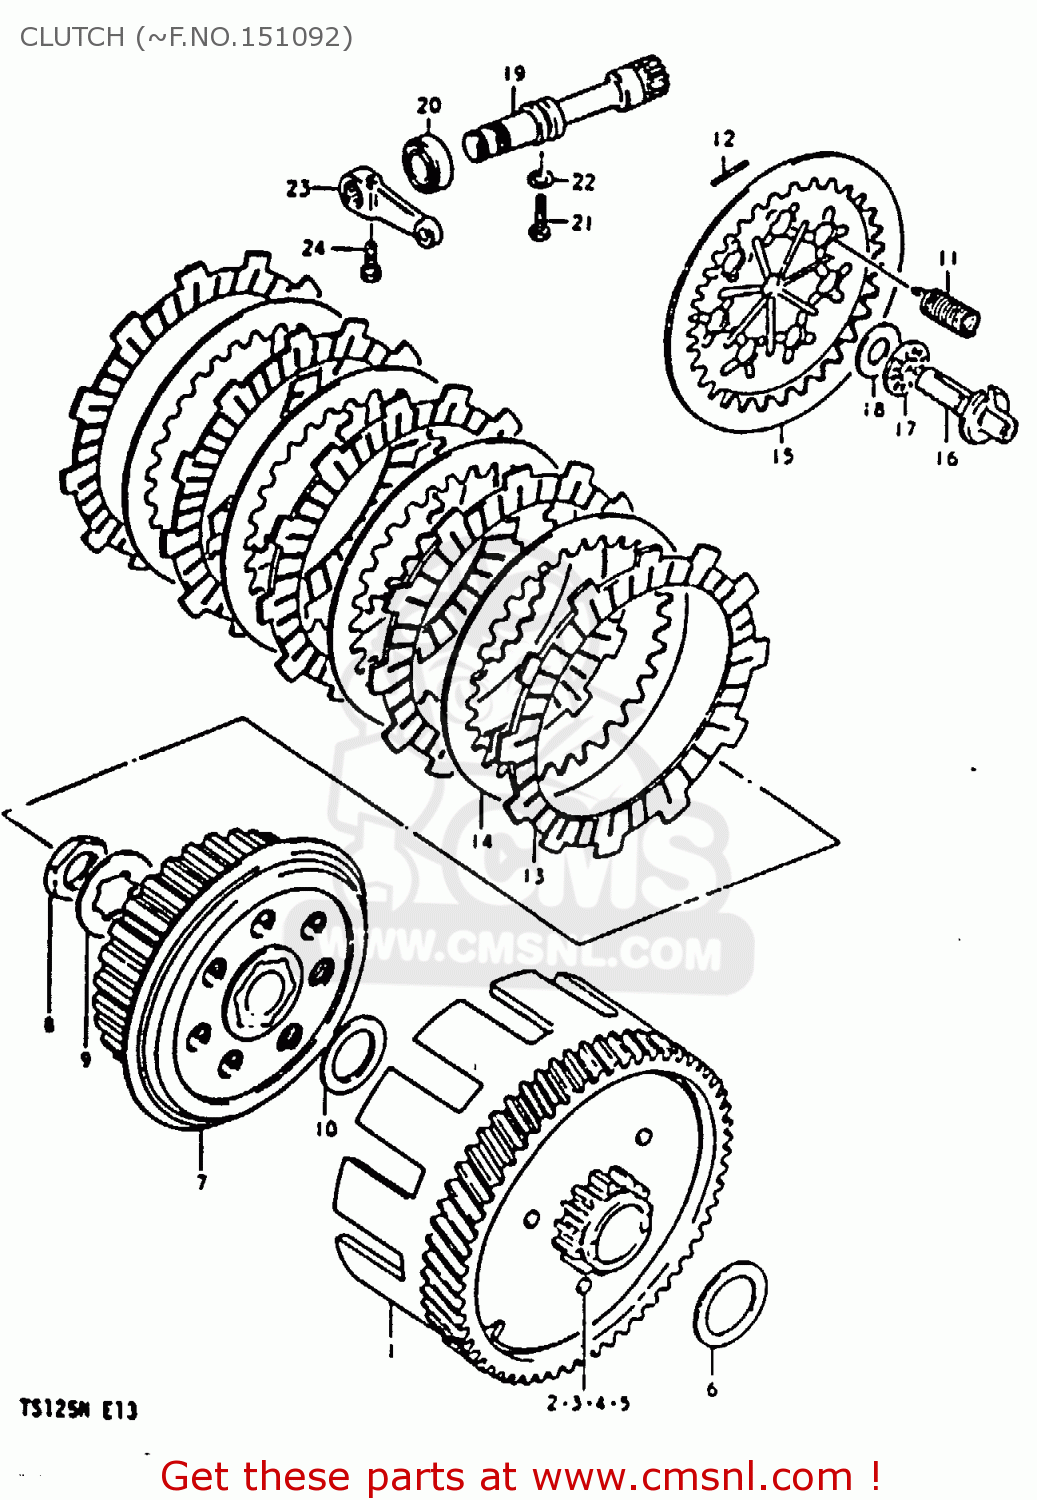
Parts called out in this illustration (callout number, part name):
1	GEAR ASSEMBLY,PRIMARY DRIVE
2	DAMPER NO.1
3	DAMPER,PRI DRIVEN GEAR NO.2
4	PLATE
5	RIVET
6	WASHER
7	HUB,CLUTCH SLEEVE
8	NUT
9	WASHER,LOCK
10	WASHER
11	SPRING
12	PIN(2.5X19.8)
13	PLATE,CLUTCH DRIVE
14	PLATE,CLUTCH DRIVEN (NAS)
15	PLATE,CLUTCH PRESSURE
16	BACK,CLUTCH RELEASE
17	BEARING(10X22X2.8)
18	WASHER(10.1X21.4X0.8)
19	PINION,CLUTCH RELEASE
20	OIL SEAL
21	BOLT(6X12)
22	WASHER
23	ARM,CLUTCH RELEASE
24	BOLT
